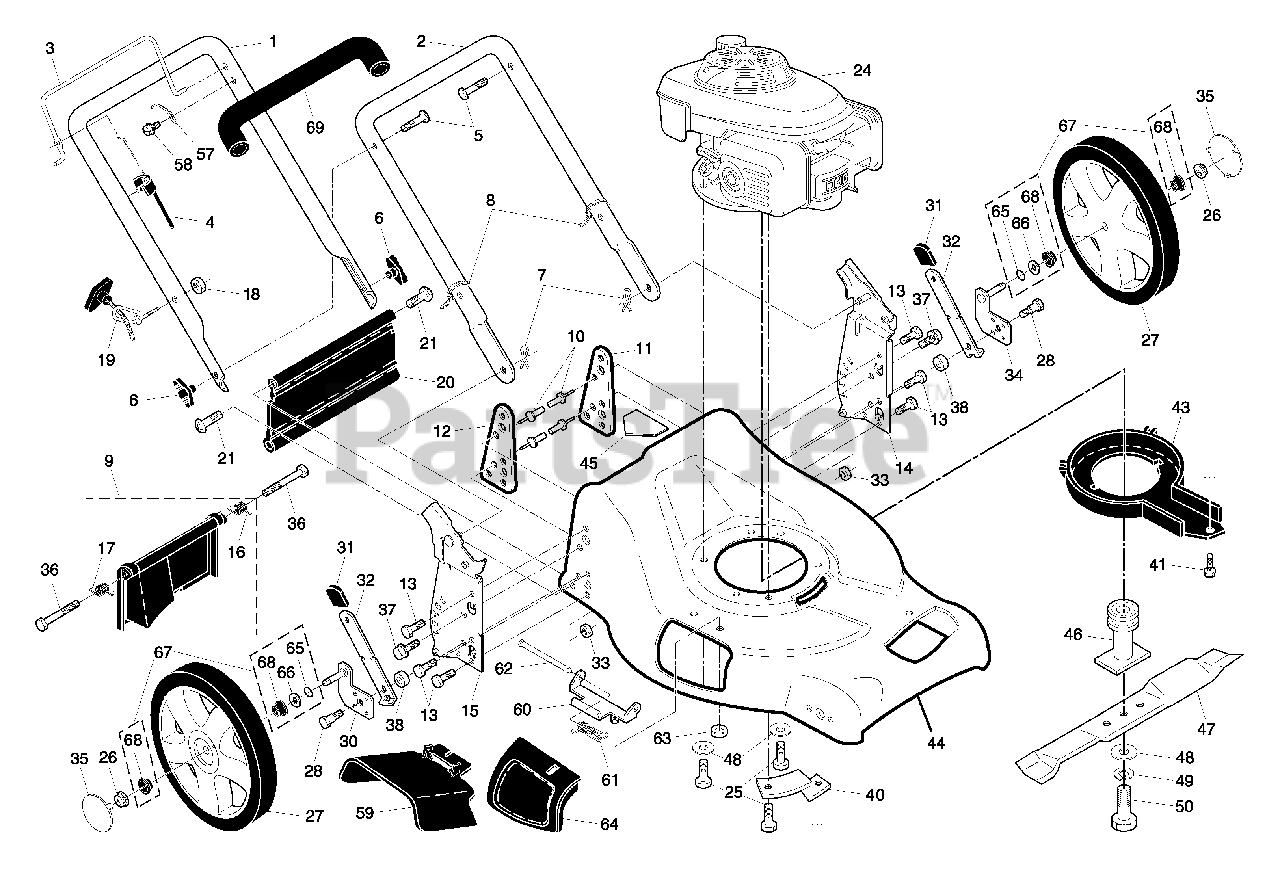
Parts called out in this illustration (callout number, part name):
1	Upper Handle
2	Lower Handle
3	Control Bar
4	Engine Zone Control Cable
5	Handle Bolt
6	Handle Knob
7	Hairpin Cotter
8	Wire Tie
9	Kit, Rear Door
11	Support Bracket, LH
12	Support Bracket, RH
13	Screw 1/4-20 x 5/8
14	Handle Bracket Assembly, LH
15	Handle Bracket Assembly, RH
16	Spring, LH
17	Spring, RH
18	Keps Locknut 1/4-20
19	Rope Guide
20	Rear Skirt
21	Screw, Tapping 1/4-20 x 1/2
25	Hex Head Thread Rolling Screw 3/8-16 x 1-1/8
26	Hex Flange Nut
27	Wheel & Tire Assembly, Rear, 14"
28	Shoulder Bolt 5/16-18 x .33
30	Axle Arm Assembly, Rear, RH
31	Selector Knob
32	Selector Spring
33	Nut, Hex 5/16-18
34	Axle Arm Assembly, Rear, LH
35	Hubcap
37	Thread Cutting Screw w/Sems 5/16-18 x 3/4
40	Mounting Bracket, Debris Shield
43	Debris Shield
44	Kit, Lawn Mower Housing
45	Danger Decal
46	Blade Adapter / Pulley
47	Blade, 21"
48	Hardened Washer
49	Helical Washer 3/8-24 x 1-3/8 Grade 8
50	Hex Head Machine Screw 3/8-24 x 1-3/8 Grade 8
57	Upstop Bracket
59	Discharge Deflector
60	Hinge Bracket
61	Spring
63	Nut, Hex
64	Mulcher Door
65	O-Ring
66	Washer, Flat 1/2
67	Kit, Bushing
68	Bushing, Nylon, Black
69	Grip, Foam
